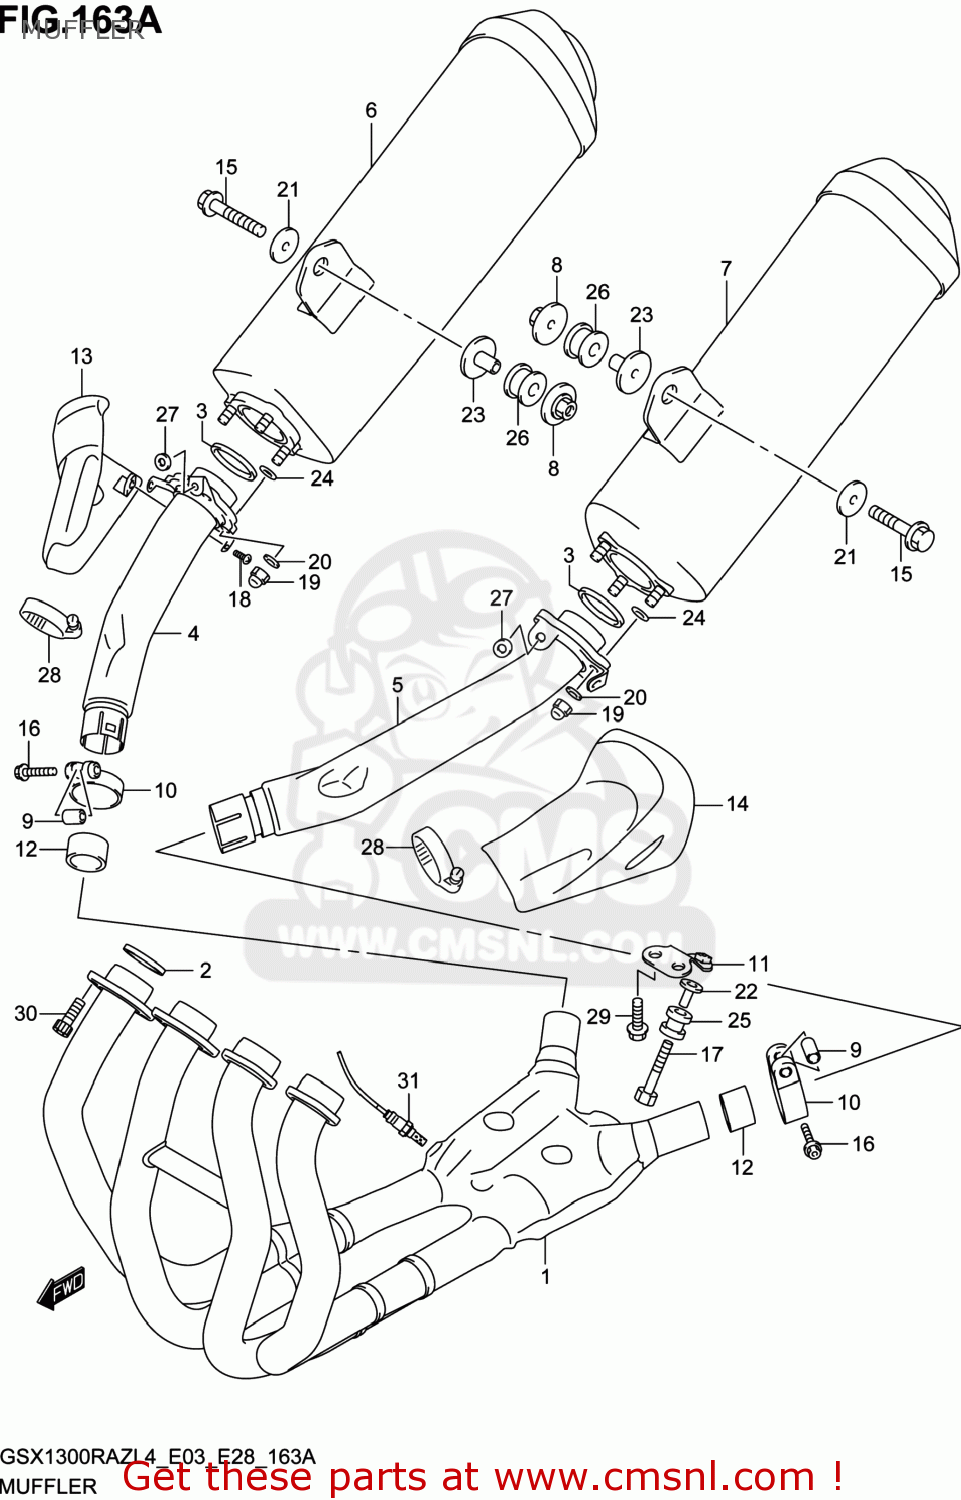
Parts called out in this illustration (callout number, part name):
1	EXHAUST
2	GASKET,EXHAUST PIPE (NAS)
3	GASKET,MUFFLER JOINT
4	PIPE,JOINT,R
5	PIPE,JOINT,L
6	BODY,MUFFLER R
7	BODY,MUFFLER L
8	NUT,MUFFLER SUPPORT RR
9	SPACER,CLAMP
10	CLAMP,CONNECTOR MUFFLER
11	BRACKET,EXHAUST SUPPORT
12	CONNECTOR,MUFFLER
13	COVER,MUFFLER FR,R
14	COVER,MUFFLER FR,L
15	BOLT(8X45)
16	BOLT(8X40)
17	BOLT(8X45)
18	SCREW(6X12)
19	NUT
20	WASHER(8.5X18X1.6)
21	WASHER(8.5X28X1.5)
22	SPACER(8.6X12X24.2)
23	SPACER(8.6X12X25)
24	O RING(D:1.9,ID:7.8)
25	CUSHION
26	CUSHION
27	CUSHION
28	CLAMP
29	BOLT
30	BOLT
31	SENSOR,OXYGEN
